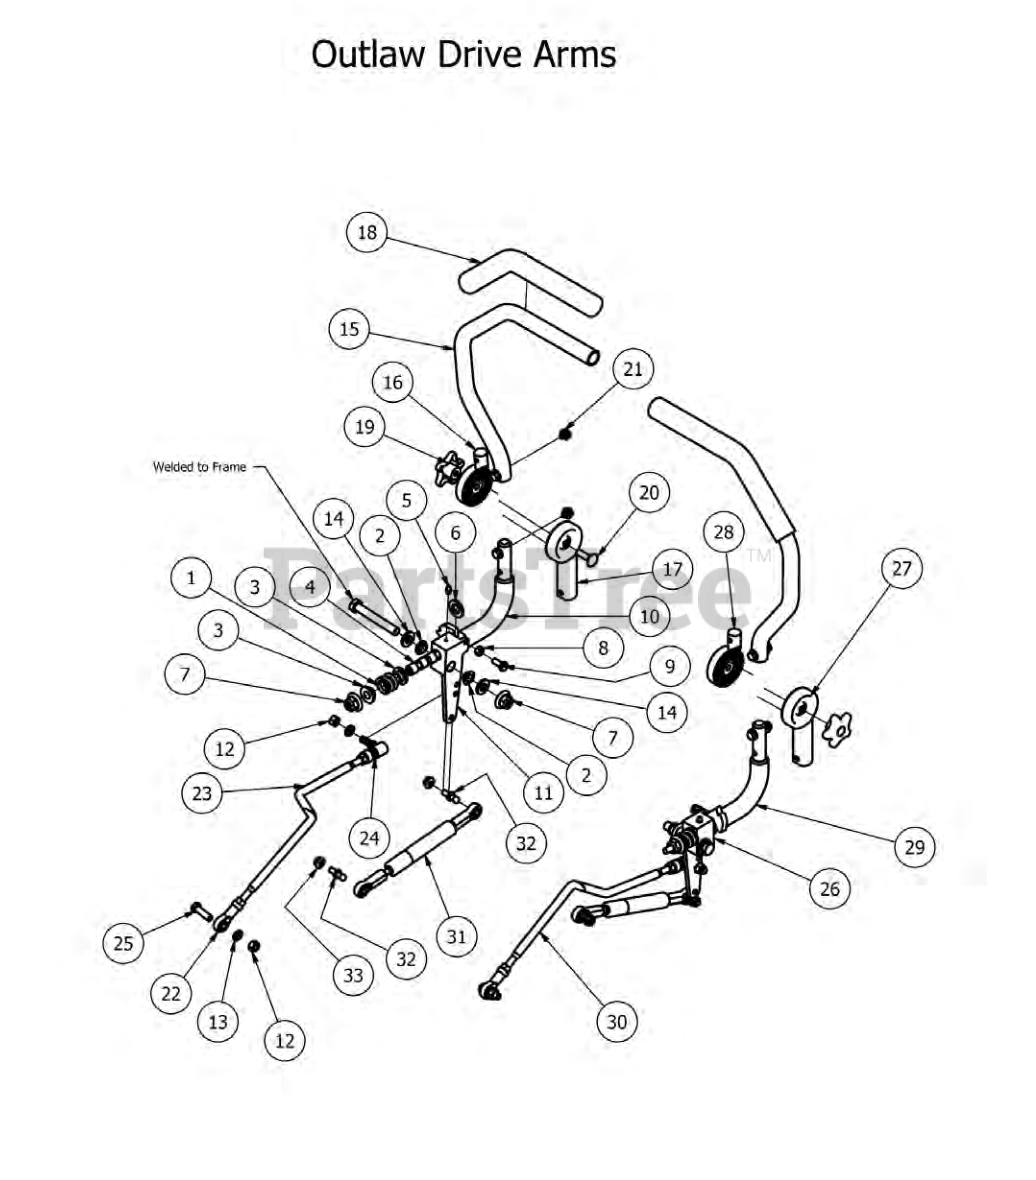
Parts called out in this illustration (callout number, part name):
1	Drive Lever Spring
2	Bushing for 2012 Drive Arms
3	.515 ID Nylon Shoulder Washer
4	507 ID Nylon Bushing
5	1/4" Drive in Grease Fitting
6	635 ID Plastic Washer
7	1/2-13 Nylon Flange Nut-Orange
9	5/16" x 3/4" Hex Bolt
10	Steering Arm Elbow - Left
11	Drive Arm Lever Housing (Left)
12	3/8" Fine Threaded Jam Nut
13	3/8" Lock Washer
14	505x1x.125 Oil Impregnated washer
15	Upper Tube-Adjustable Steering
16	Upper adjuster-Steering Arm- Left
17	Lower Adjuster - Steering Arm- Left
18	Rubber Grip
19	Black Knob for Adjustable Steering Arm
20	3/8" x 1 1/4" Carriage Bolt
21	5/16-18 1/2 HWH Bolt-Steering
22	Spherical Rod End - Outlaw
23	Push Rod for Outlaw - Left
24	Quick Release Ball Joint
25	3/8" x 1 1/4" Hex Bolt
26	Drive Arm Lever Housing (Right)
27	Lower Adjuster -Steering Arm- Right
28	Upper Adjust Steering Arm- Right
29	Steering Arm Elbow - Right
30	Push Rod for Outlaw - Right
32	10mm Damper Ball Stud-Steering
33	5/16" Flange Nut
